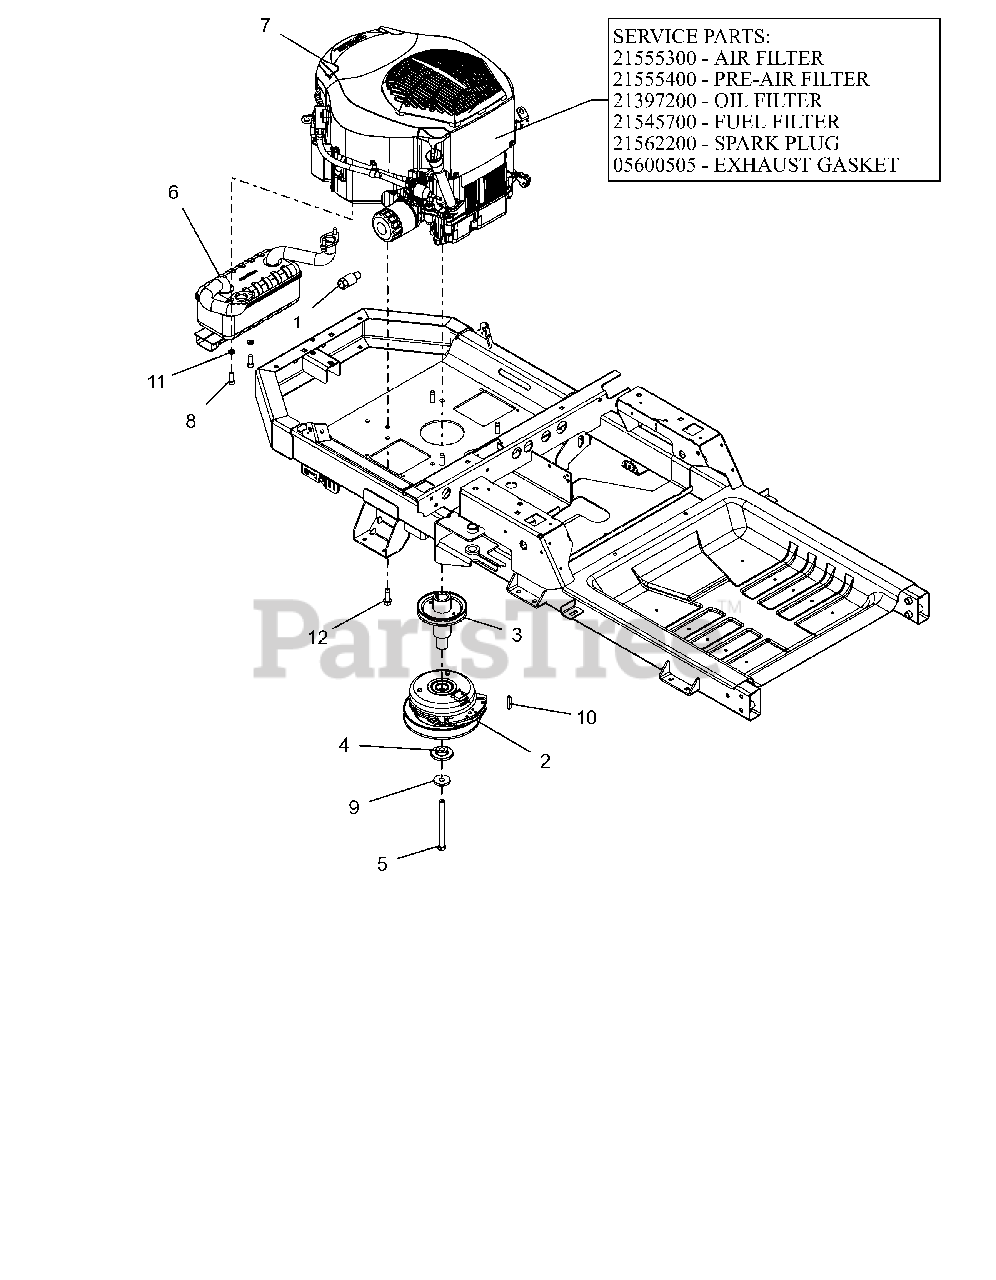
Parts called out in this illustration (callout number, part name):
1	DRAIN, OIL
2	CLUTCH,105FTLB MONOPOLE 6.83"
3	WLDMT, DRIVE SHEAVE (LG XL)CZC
4	BSHG-FLG .469X1.06X.574X2.0
5	BLT-HEX.438-20X5 GR8 YZ NYTORQ
6	MUFFLER, KOHLER
7	ENGINE, KOHLER 26 HP PRO W/SC
7	AIR FILTER, KOHLER
7	PRE CLEANER, KOHLER
7	FILTER, OIL - KOH CV20
7	FILTER-FUEL KOHLER COURAGE PRO
7	PLUG, SPARK (RFI)
7	GASKET, MUFFLER KOHLER TWIN
8	SCR, SKH .312-18X.875 GR8 ZCC
9	WASHER, 7/16" SPRING DISK
10	KEY-SQ .25 X 1.25 X .25 SAE
11	WSHR,LK-REG .312X.078 ZCC
12	SCR,TAP .375-16X1.25HWH TR ZCC
